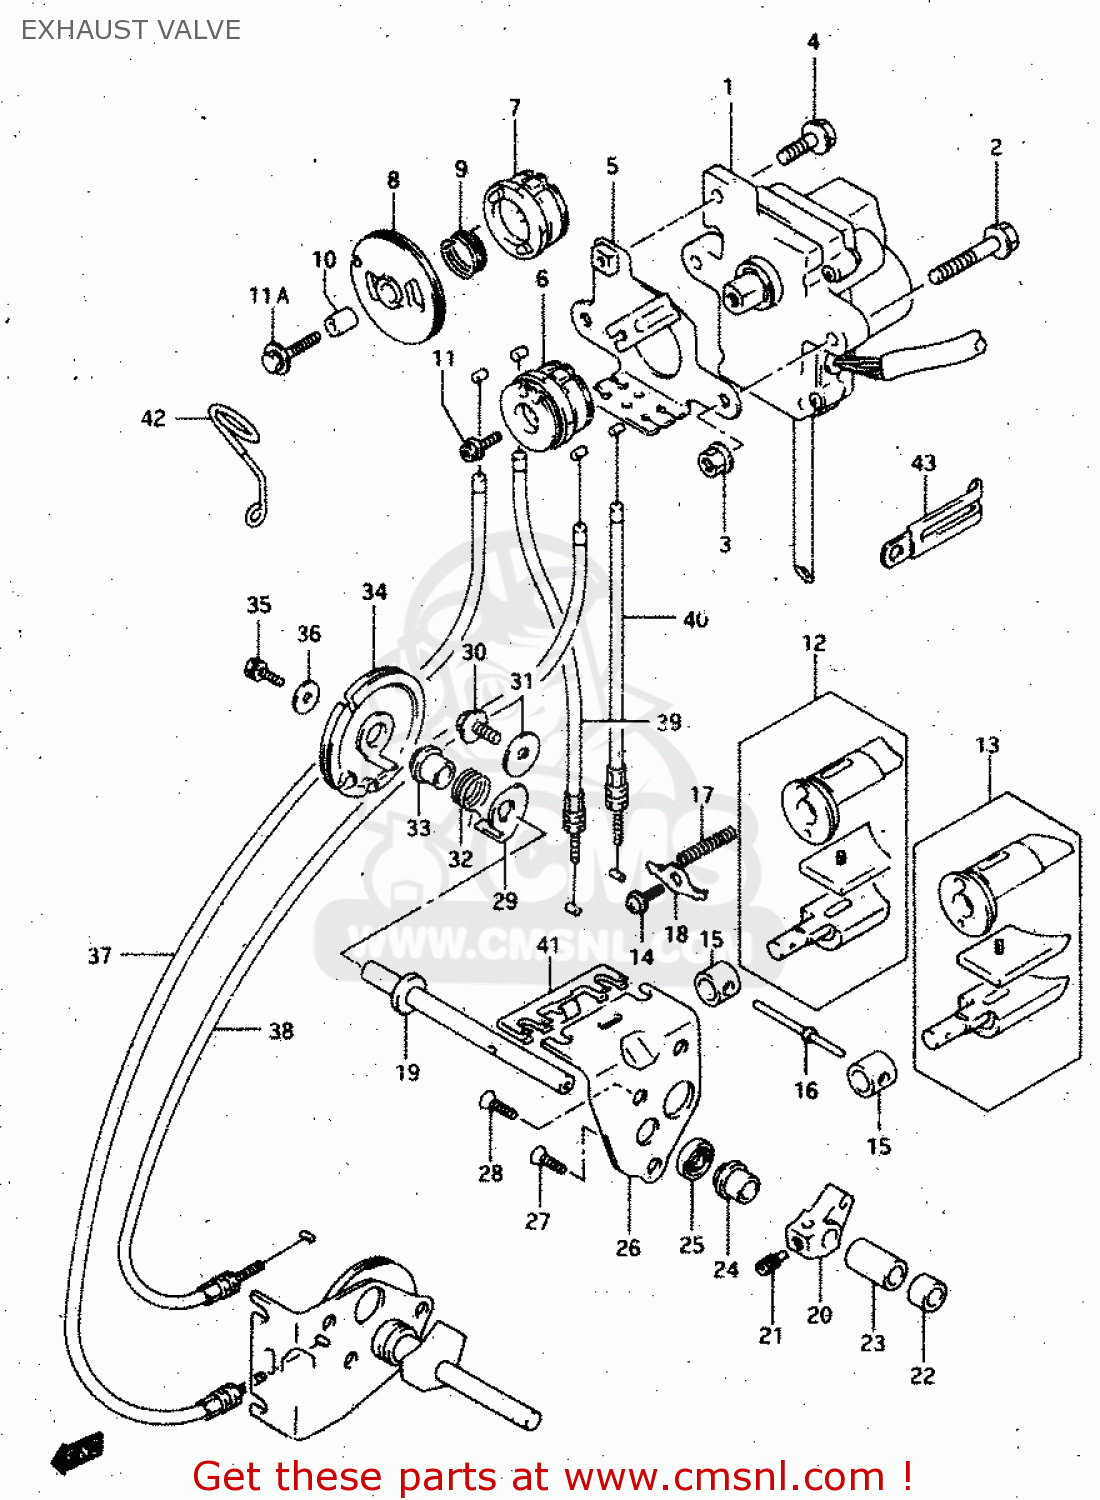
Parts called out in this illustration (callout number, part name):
1	ACTUATOR ASSY
2	BOLT
3	NUT
4	BOLT
5	BRACKET,CABLE
6	PULLEY, CONTROLLER
7	PULLEY,CONTROLLER
8	PULLEY,CONTROLLER NO.2
9	SPRING
10	SPACER
11	BOLT
11A	BOLT(5X30)
12	VALVE SET,EXHAUST,R
13	VALVE SET,EXHAUST,L
14	SCREW
15	SPACER,EXHAUST VALVE
16	PIN,EXHAUST VALVE 48.5MM
17	SPRING
18	RETAINER,EXHAUST VALVE SPRING
19	SHAFT,EXHAUST VALVE
20	ARM,EXHAUST VALVE SHAFT
21	SCREW(6X10)
22	BUSH(8X12X7)
23	SPACER,EXHAUST VALVE SHAFT
24	BUSH,EXHAUST VALVE NO.2
25	SEAL,OIL(8X16X5)
26	RETAINER,OIL SEAL
27	SCREW
28	SCREW(6X12)
29	LEVER,EXHAUST VALVE
30	SCREW (6X10)
31	WASHER
32	SPRING,EXHAUST VALVE LEVER
33	SPACER,EXHAUST VALVE PULLEY
34	PULLEY,EXHAUST VALVE
35	BOLT
36	WASHER (5.5X24X1.6)
37	CABLE,EXHAUST VALVE FR,R
38	CABLE,EXHAUST VALVE FR,L
39	CABLE,EXHAUST VALVE RR,R
40	CABLE,EXHAUST VALVE RR,L
41	STOPPER,CABLE
42	GUIDE,EXHAUST VALVE CABLE
43	CLAMP
